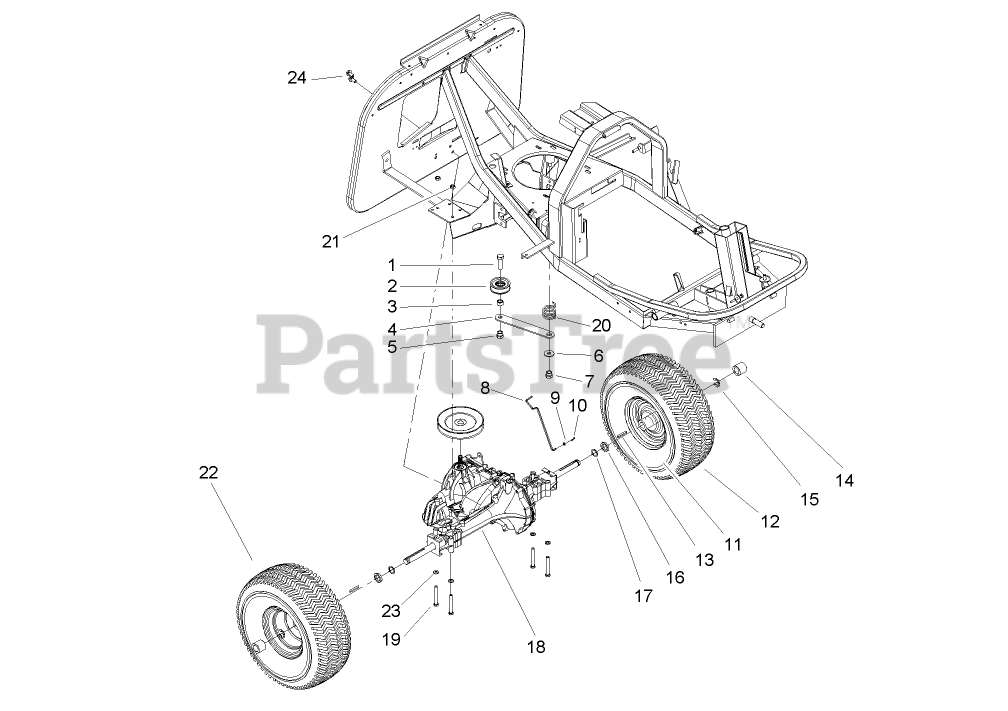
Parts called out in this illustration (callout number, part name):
1	SCREW-HH
2	PULLEY ASM
3	Spacer-Idler
4	Bracket
5	NUT-LOCK
6	Washer-Flat
7	NUT-LOCK, NI
9	Washer-Flat
10	Pin-Hair
11	WHEEL-LH
13	Key-Square
14	Spacer
15	RING-RETAINING, EXT
16	Spacer
17	Washer-Flat
18	TRANSAXLE-HYDRO
19	Screw-HH
20	Spring-Extension
21	NUT-LOCK
22	WHEEL-RH
23	WASHER-PLAIN
24	SCREW-HHF TAP
